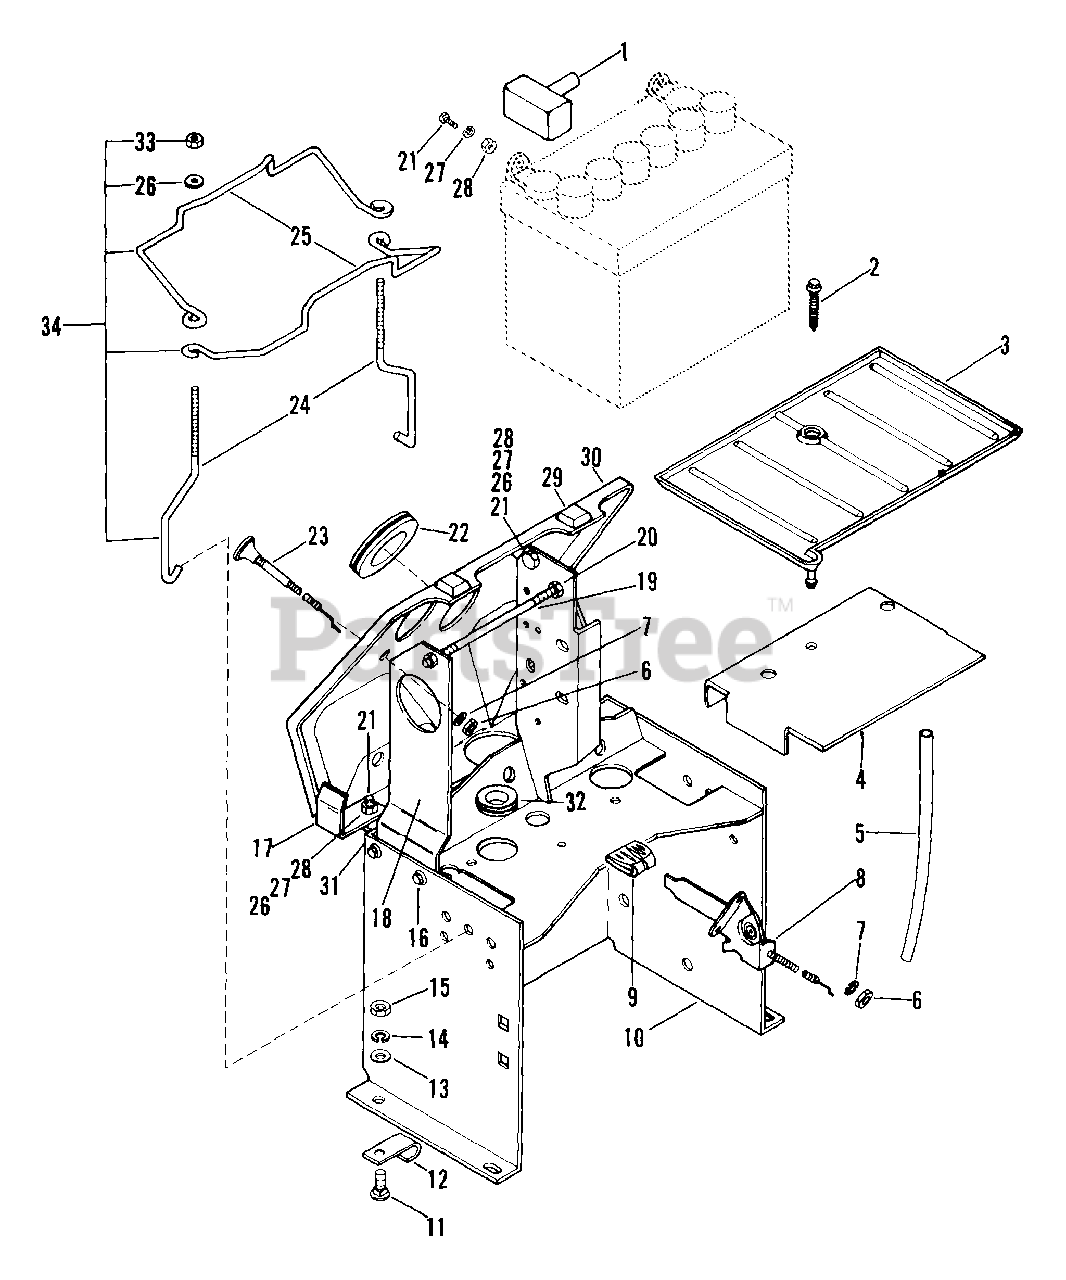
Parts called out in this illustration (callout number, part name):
1	INSULATOR
2	SCR-TAP 12-14X1.50 CROVH PL BT
3	BATTERY TRAY
4	BATTERY STAND
4	BATTERY STAND WELD'T
5	DRAIN HOSE
6	NUT-HEX 10-24 PL
7	WSHR-LK-EXT #10 ID X .022
8	THROTTLE CONTROL
8	THROTTLE CABLE
10	DASH SUPPORT
10	DASH SUPPORT MS
10	DASH SUPPORT PS
11	BLT-RDHDSQNK .31-18X.75 GR5 PL
12	J-CLAMP
13	WSHR-FL-STL.344X.688X.065PL
14	WSHR-LK .312X.097 PL HVY
15	NUT-HEX .312-18
16	SCR-TAP .250-20X.50 HXSLHDPL
18	HOUR METER MOUNTING PLATE
19	BRACE ROD
20	NUT-LK-FLG .250-20 PL
21	BLT-HEX .25-20X.75 PL GR2
22	GROMMET
23	CHOKE CONTROL
24	J-BOLT
24	TIE DOWN
25	HOLD DOWN
25	BATTERY TIE DOWN
26	WSHR-FL-STL.281X.62X.065 PL
27	WSHR-LK .250X.077 HVY PL
28	NUT-HEX .250-20 PL
29	STOP
30	DIESEL DASH
30	DASH
31	SCR-TAP 10-24X.375 HWH PL TR
32	GROMMET 1.0ID X 1.38 OD
33	NUT-LK-NYL .250-20 PL
34	BATTERY HOLD DOWN ASSEMBLY
